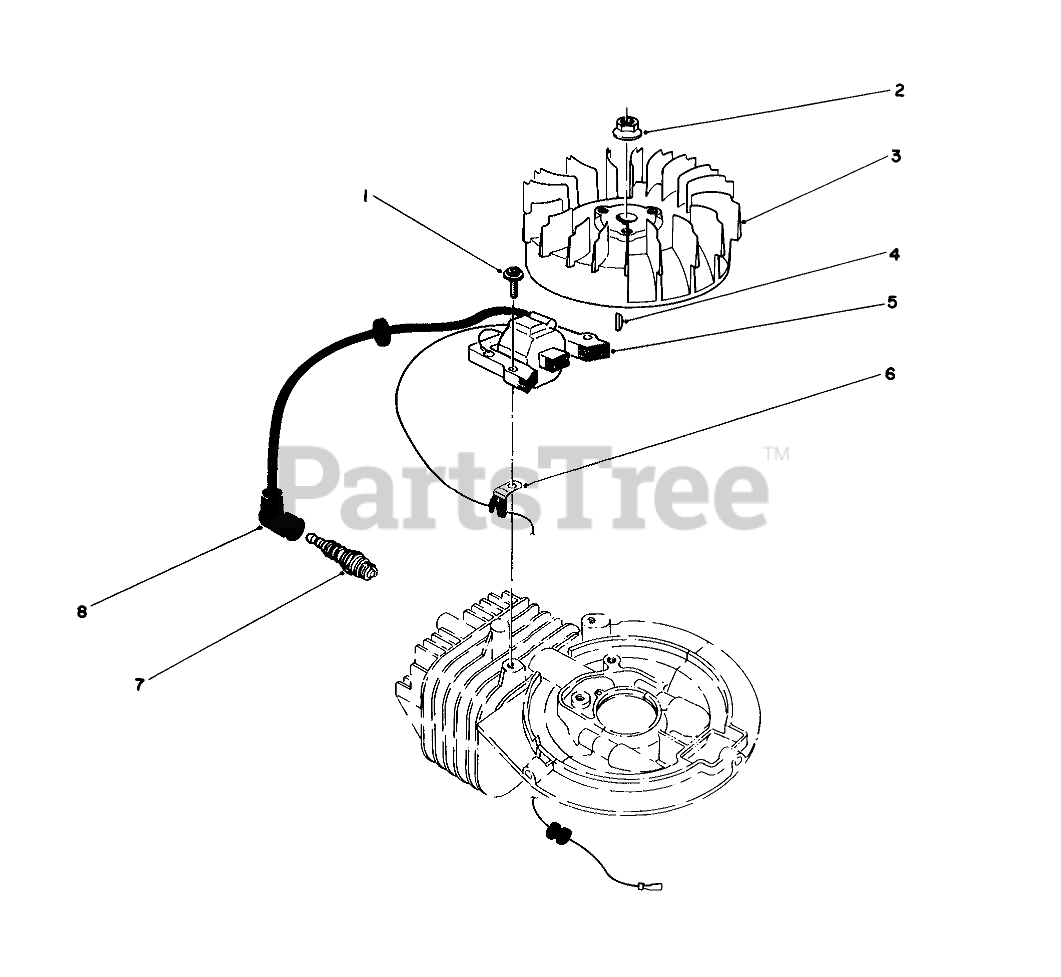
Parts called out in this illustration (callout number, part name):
1	Allenhead
3	FLYWHEEL
5	COIL-MAGNETO
6	CLAMP
7	Sparkplug
8	CAP-SPARKPLUG
